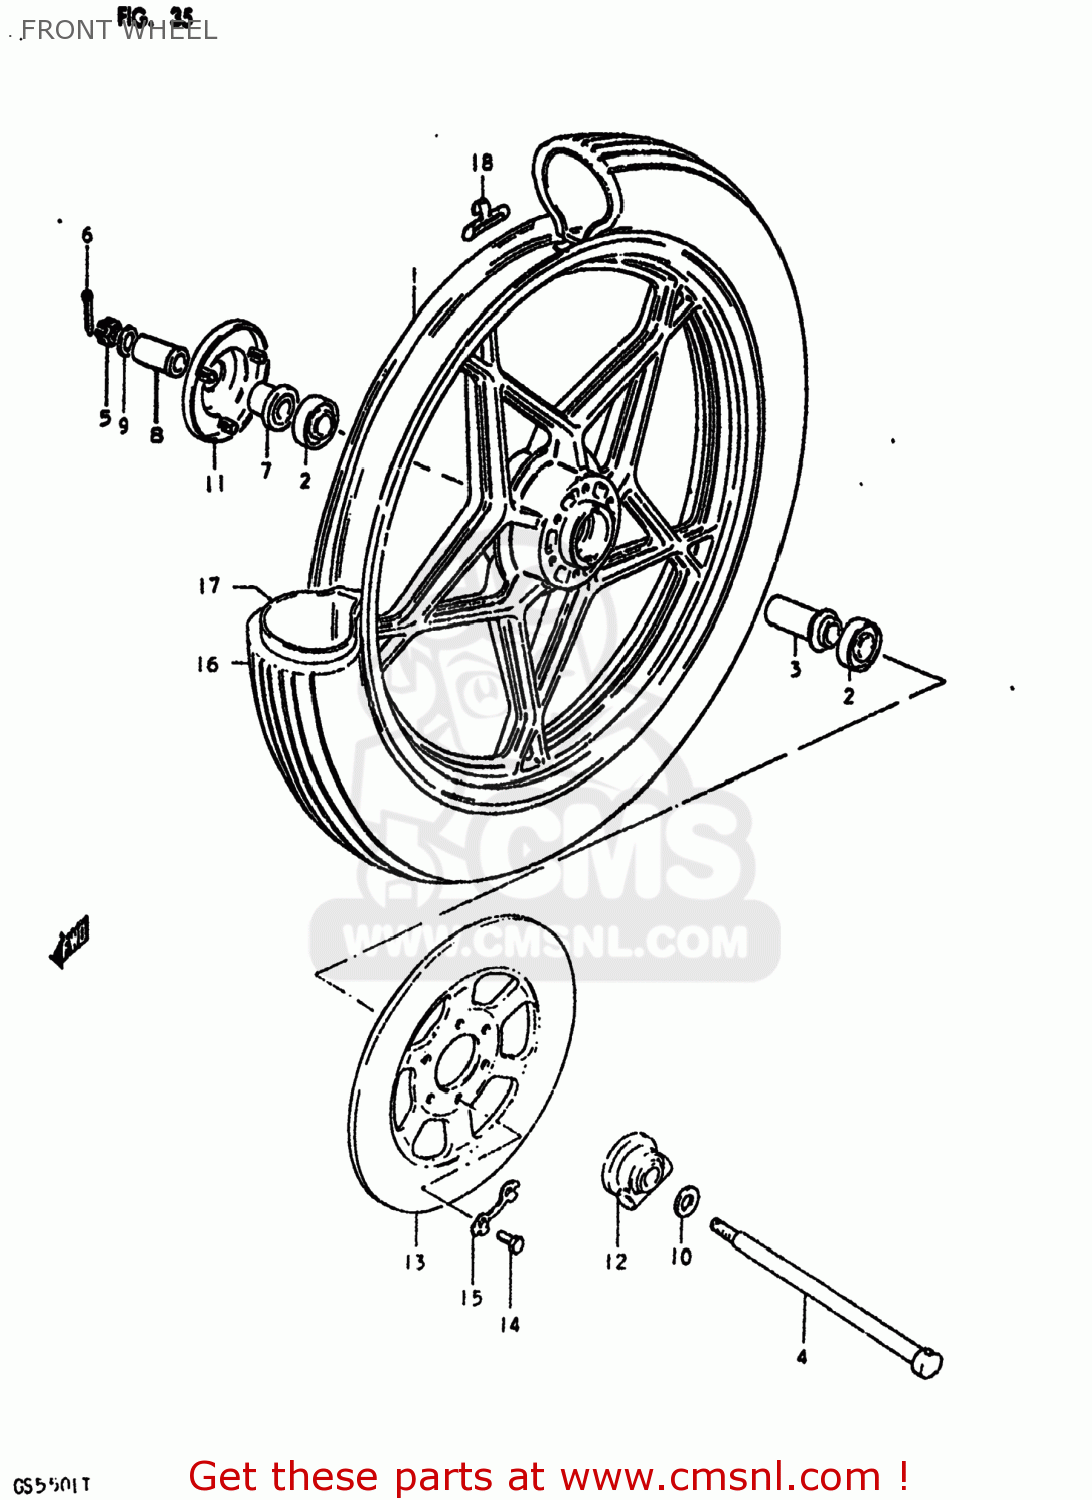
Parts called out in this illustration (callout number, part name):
1	WHEEL, FRONT
2	BEARING
3	SPACER,FR HUB BEARING
4	AXLE,FR
5	NUT 12MM
6	COTTER PIN
7	SPACER,FR AXLE,R
8	SPACER
9	WASHER
10	WASHER(15.5X26X2.3)
11	COVER,FR HUB,R
12	BOX ASSY,SPEEDOMETER GEAR
13	DISC,BRAKE
14	BOLT(8X25)
15	WASHER
16	TIRE 3.25H19 083X483MM
17	TUBE,INNER
18	BALANCER,WHEEL
